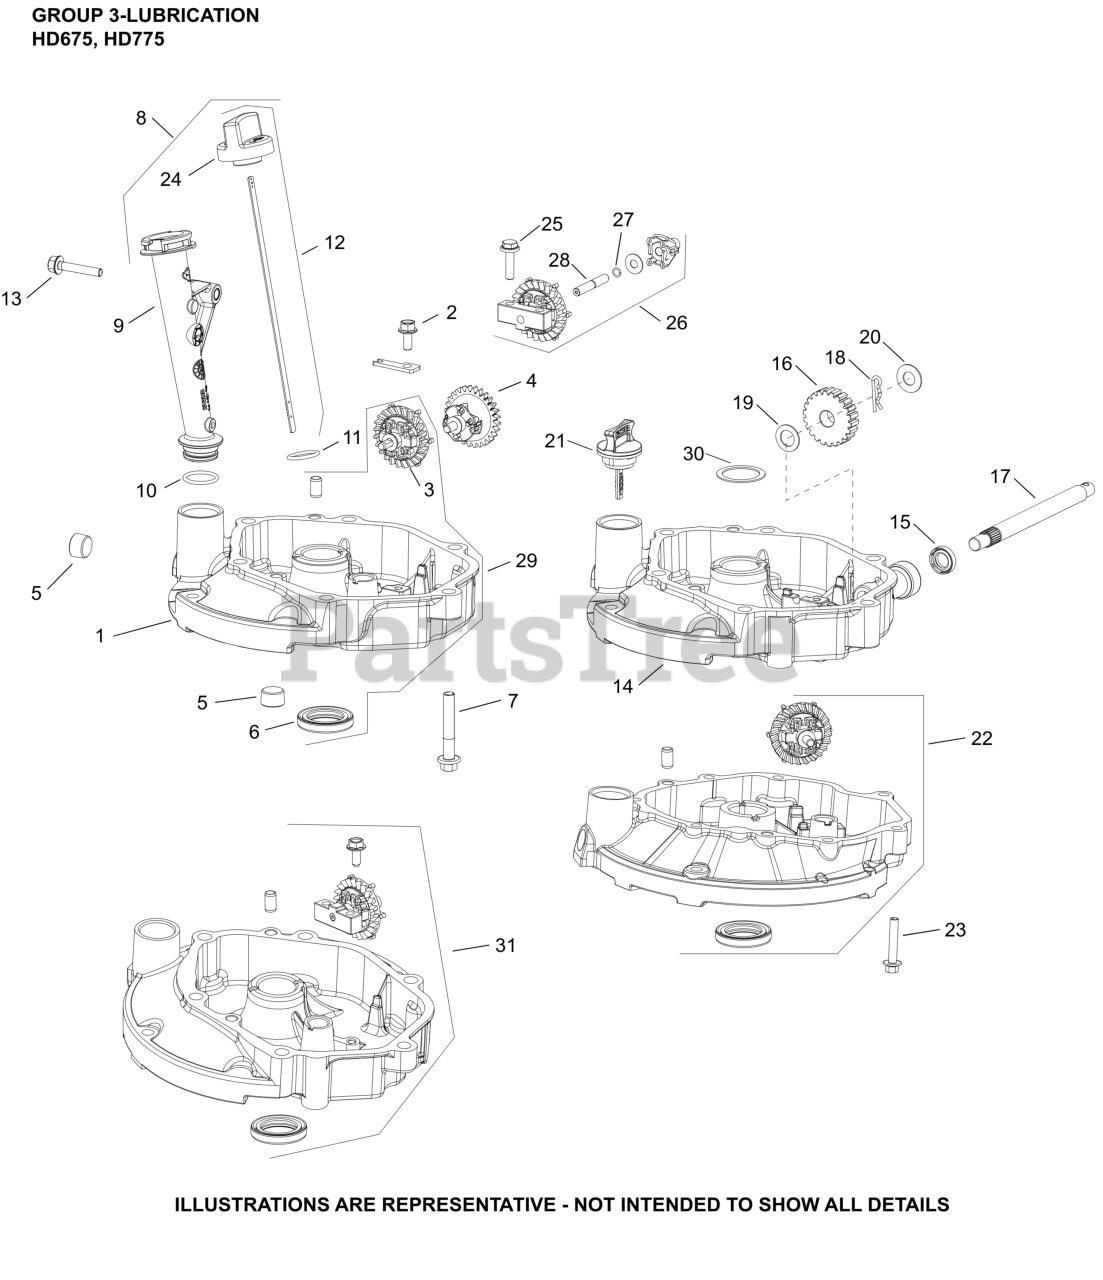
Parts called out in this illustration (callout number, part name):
3	GEAR ASSEMBLY, GOVERNOR
5	PLUG, PIPE (W/SEALANT)
7	SCREW, HEX FLANGE (M8)-USE 25 086 456-S
8	TUBE ASSEMBLY OIL FILL
10	O-RING, OIL FILL TUBE
11	O-RING (CAP)
13	SCREW, HEX FLANGE (M6)-(#25086435S)
14	KIT, OIL PAN
15	SEAL, OIL
16	GEAR, 2ND PTO
17	SHAFT, DRIVE SECOND PTO
18	CLIP, GOVERNOR ARM
